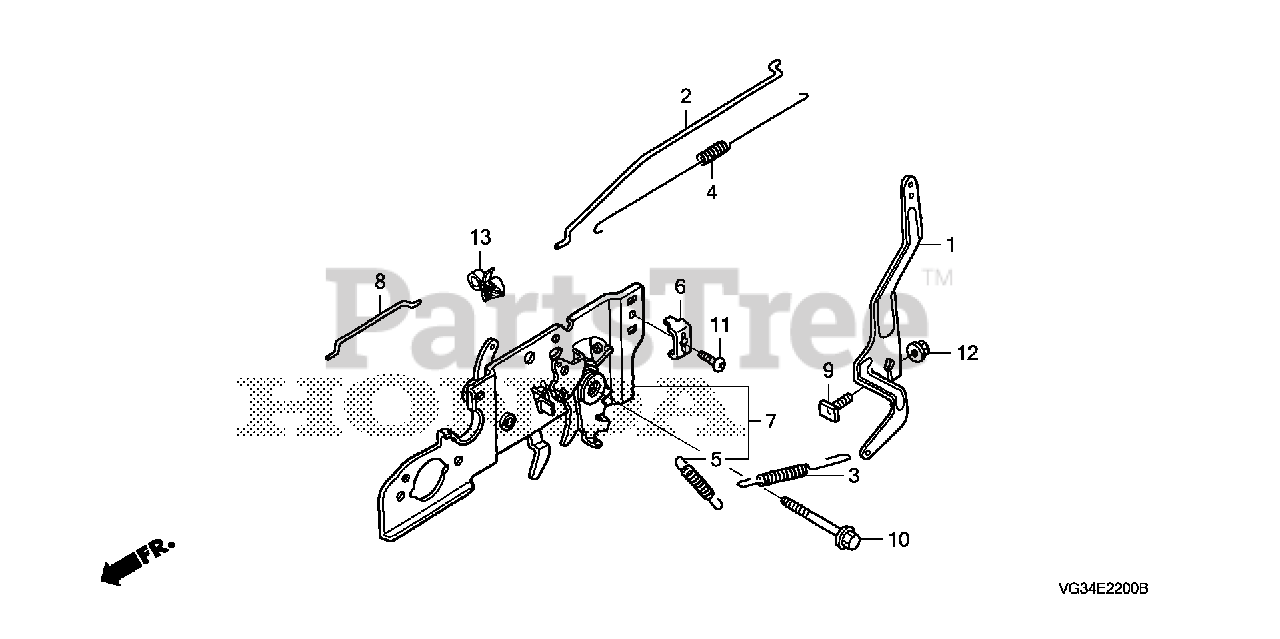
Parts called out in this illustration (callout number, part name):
1	ARM, GOVERNOR
2	ROD, GOVERNOR
3	SPRING, GOVERNOR
4	SPRING, THROTTLE RETURN
5	SPRING, LEVER
7	BASE, CONTROL
8	ROD, CHOKE
9	BOLT, GOVERNOR ARM
10	BOLT, FLANGE (6X45) (CT200)
12	NUT, FLANGE (6MM)
